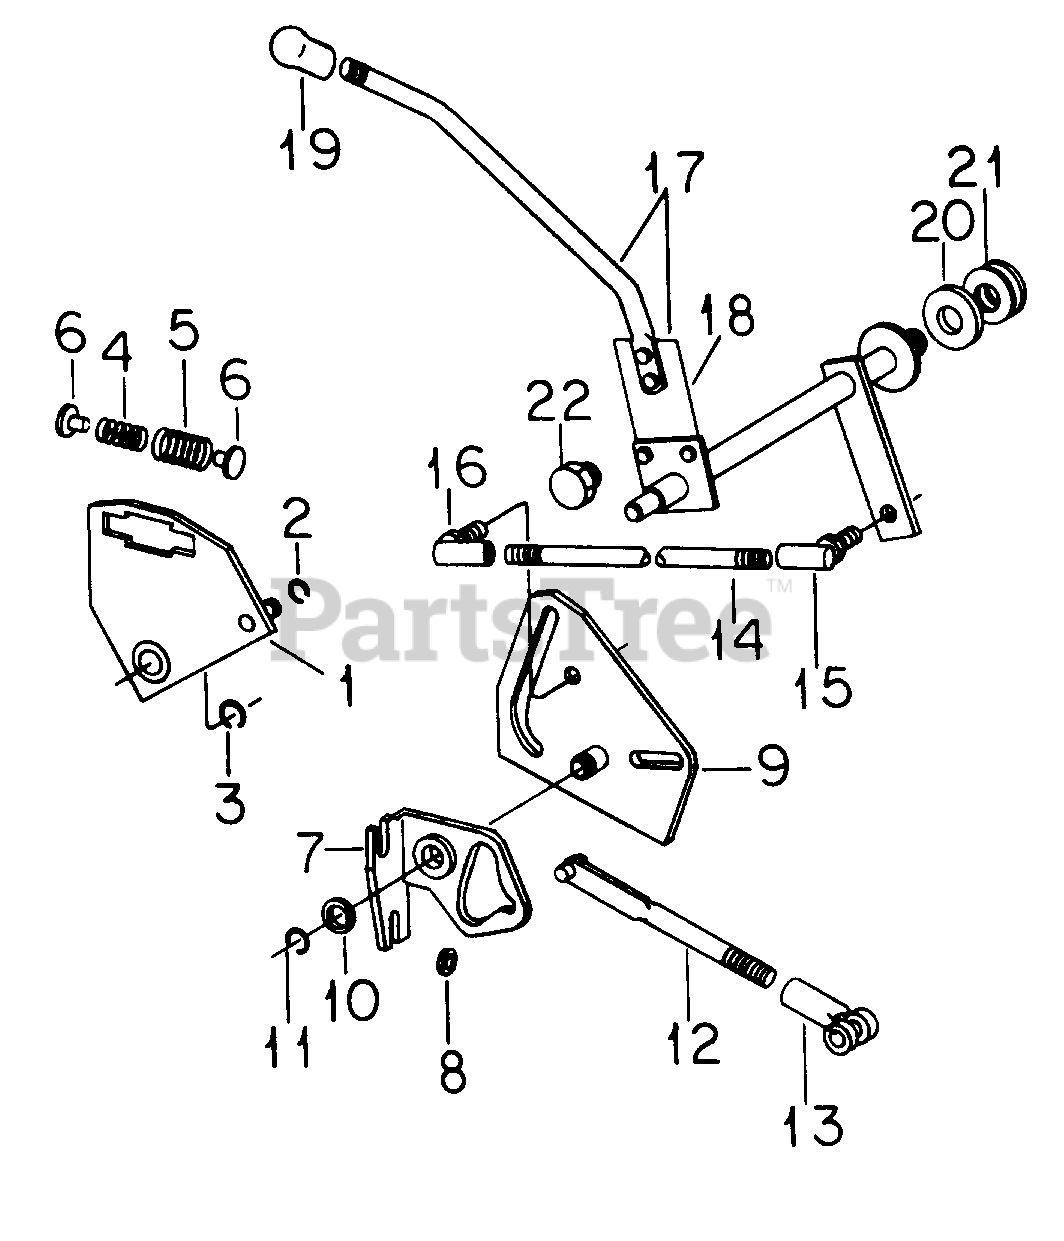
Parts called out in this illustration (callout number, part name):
1	Plate Assy, Damper Spring
2	Ring, Retaining
3	Ring, Retaining
4	Spring, Damper LT
5	Spring, Damper HV
6	Pin, Damper Spring Guide
7	Bracket Assy, Cam Pivot
8	Washer, .406 X .812 X .065
9	Cam Assy, Control
10	Washer, Cam Retaining
11	Ring, Cam Retaining
12	Rod Assy, Control
13	Clevis, 3/8 Rod End
14	Stud, Connecting
15	Joint, 5/16-24 Znd Ball
16	Joint, 5/16-24 Znd Ball
17	Shaft Assy, Cross
18	Spring, Flat
19	Knob, Control
20	Disc, Friction
21	Washer, Belleville
22	Bearing, Rockshaft
